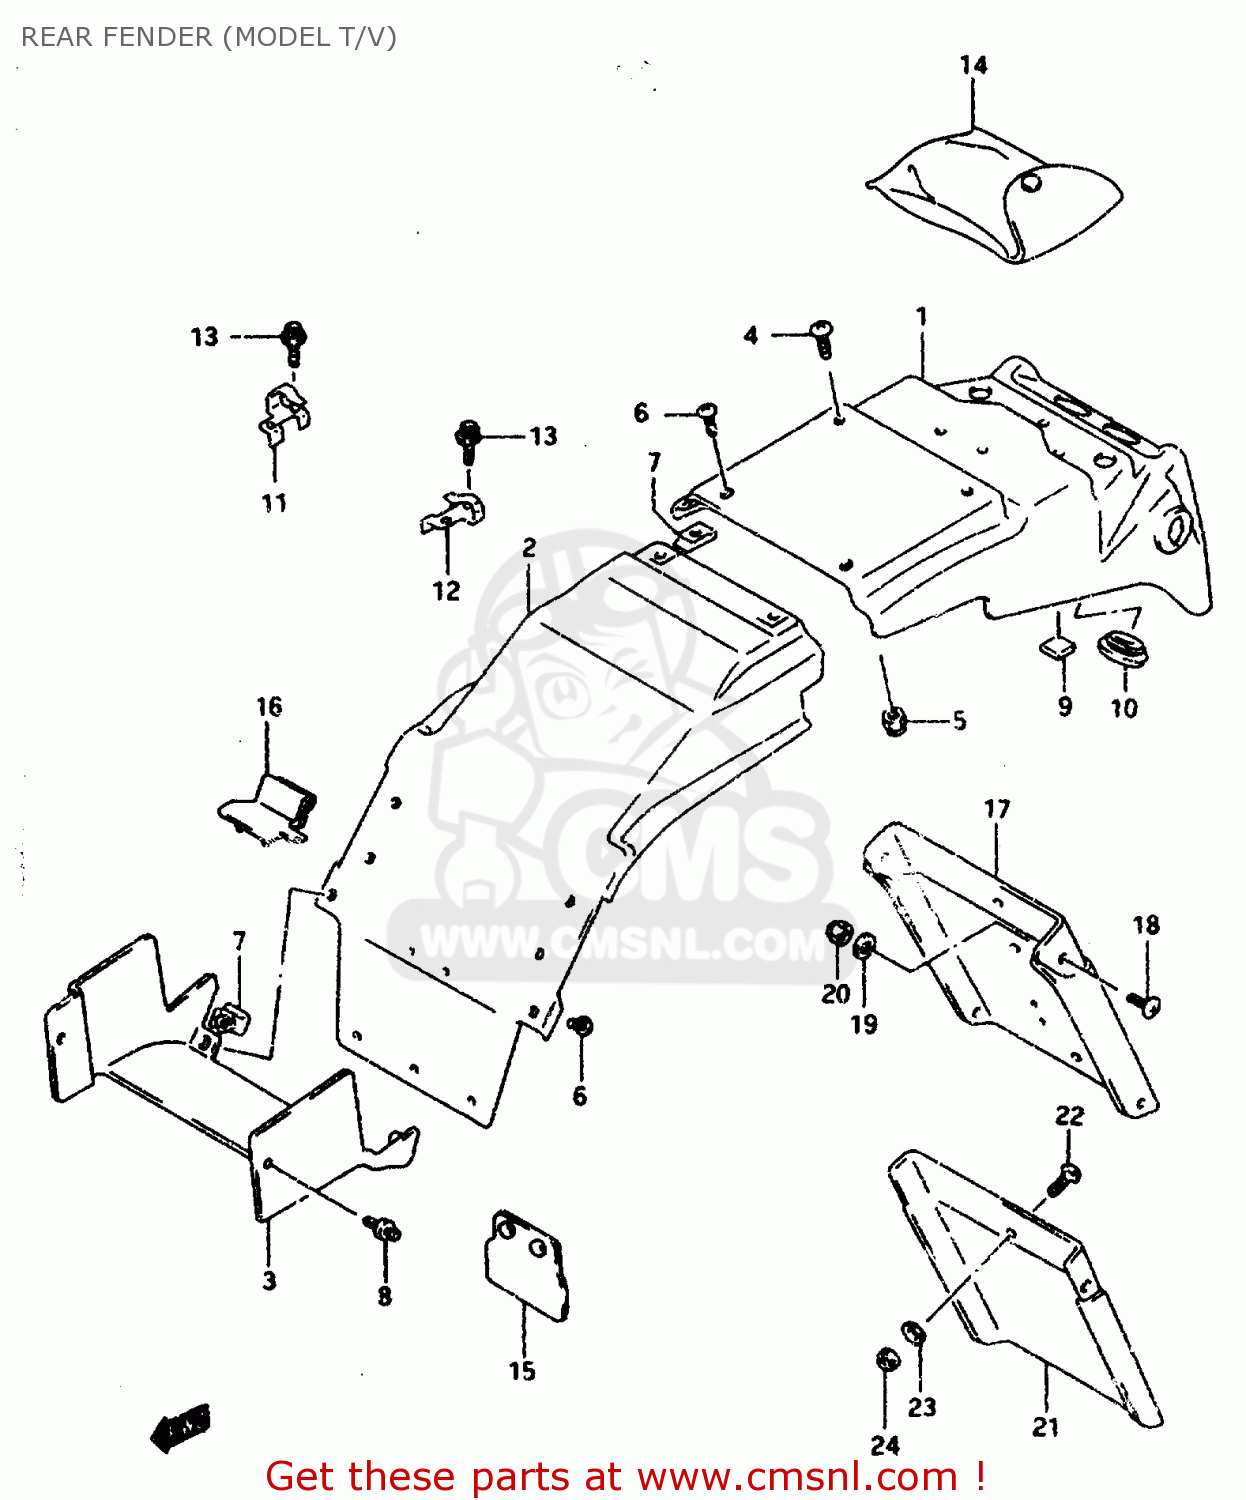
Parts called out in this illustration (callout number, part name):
1	FENDER,RR UPR
2	BODY,RR FENDER UPR FR NO2
3	FENDER,RR UPR FR NO.1
4	SCREW
5	NUT
6	SCREW 5X12
7	NUT,HEADLAMP HOUSING,UPPER
8	CLIP(BLACK)
9	TAPE,REAR COMBINATION LAMP HOLE
10	CAP OD:40
11	HOLDER,HELMET,R
12	HOLDER,HELMET,L
13	BOLT
14	TOOL ASSY
15	GUIDE,RR FENDER MUD
16	MUD GUARD,REAR FENDER
17	EXTENSION,RR FENDER
18	SCREW
19	WASHER
20	NUT
21	MUD GUARD, REAR FENDER
22	NUT
23	MUD GUARD, REAR FENDER
24	NUT
25	WASHER
26	NUT
